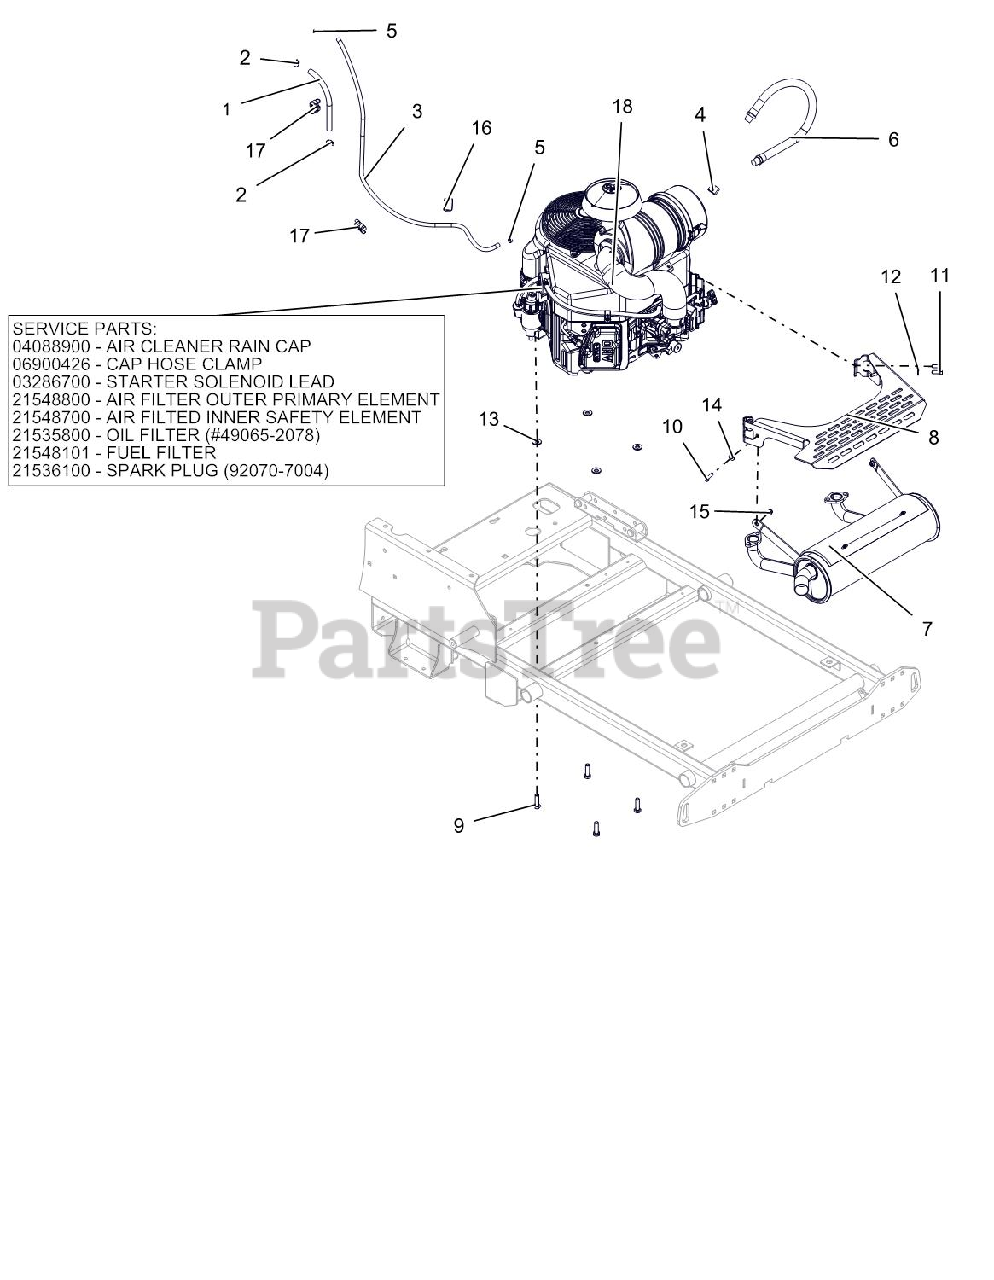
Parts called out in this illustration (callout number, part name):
1	HOSE, .25 LOW-PERM BULK GAS
2	CLAMP, FUEL LINE
3	HOSE, .188 LOW-PERM BULK GAS
4	PIPE CAP 3/8 NPT FEMALE
5	CLAMP-HOSE, SPRING .188
6	DRAIN, M20 OIL
7	EXHAUST, KAWASAKI PROSTANCE
8	SHIELD, MUFFLER
9	BLT-HEX.38-16X1.25 G5YZ NYTORQ
10	BLT-HEX .25-20X1.00 GR5 YWZC
11	BLT-HEX M8-1.25X20 YWZC
12	WSHR-LK .31X.078 REG YWZC
13	WASHER, 3/8" SPRING DISC
14	WSHR-FL-STL.281X.62X.065 YWZC
15	NUT-LK-NYL-FLG .25-20 YWZC
16	CLAMP, COUSHIONED STEEL REV
17	CLIP, T, .38-.50
18	FILTER,OIL - KAW
18	PLUG, SPARK
18	LEAD - STARTER SOLENOID
18	CAP, KAW 11065-7025
18	CLAMP, HOSE #36 SS 1.813-2.75
18	FILTER, OUTER
18	FILTER, INNER - KAW
18	ENGINE, KAWASAKI FX730
18	FUEL FILTER-KAWASAKI FR
